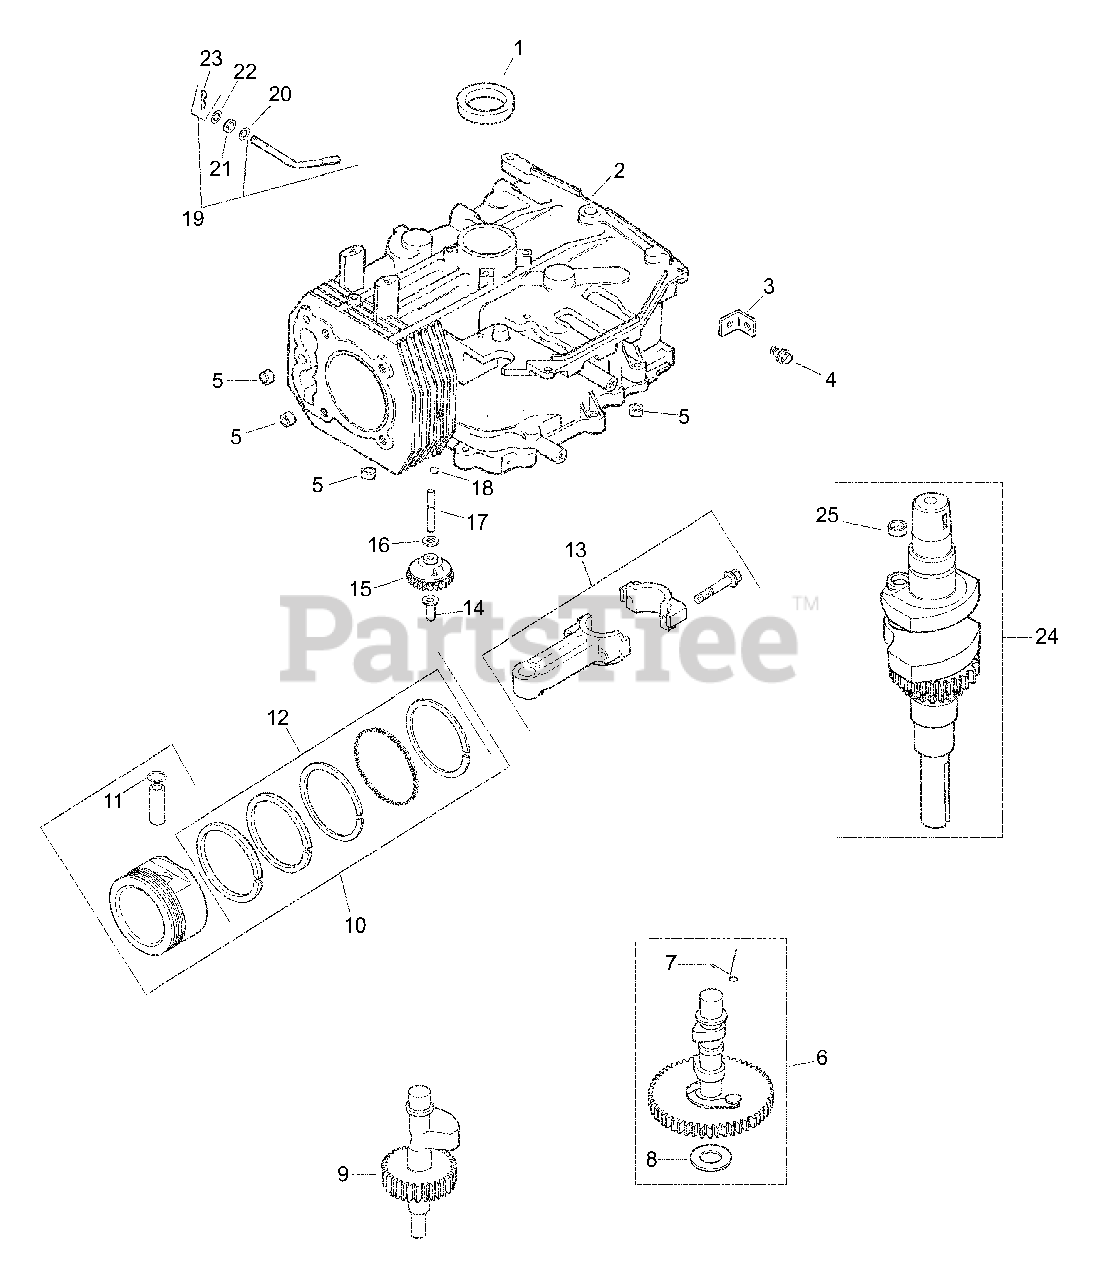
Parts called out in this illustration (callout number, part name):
1	Seal, Crankshaft
2	Crankcase (Short Block)
3	Strap, Lifting
4	Screw, Hex. Flange M8 X 1.25 X 25
5	Pin, Locating
6	Kit, Camshaft
7	Spring, Actuating
8	Shim, Camshaft - Blue
9	Shaft, Balance
10	Piston w/ Ring Set (Std.)
11	Retainer, Piston Pin
12	Ring Set (Std. & .08)
13	Connecting Rod (Std.)
14	Pin, Governor Regulating
15	Gear, Governor
16	Washer, Plain 6 Mm
17	Shaft, Governor Gear
18	Plug, Cup
19	Kit, Governor Cross Shaft w/clip
20	Washer, Plain 1/4"
21	Seal, Governor Cross Shaft
22	Washer, Plain 6 Mm
23	Clip, Hitch Pin
24	Crankshaft
